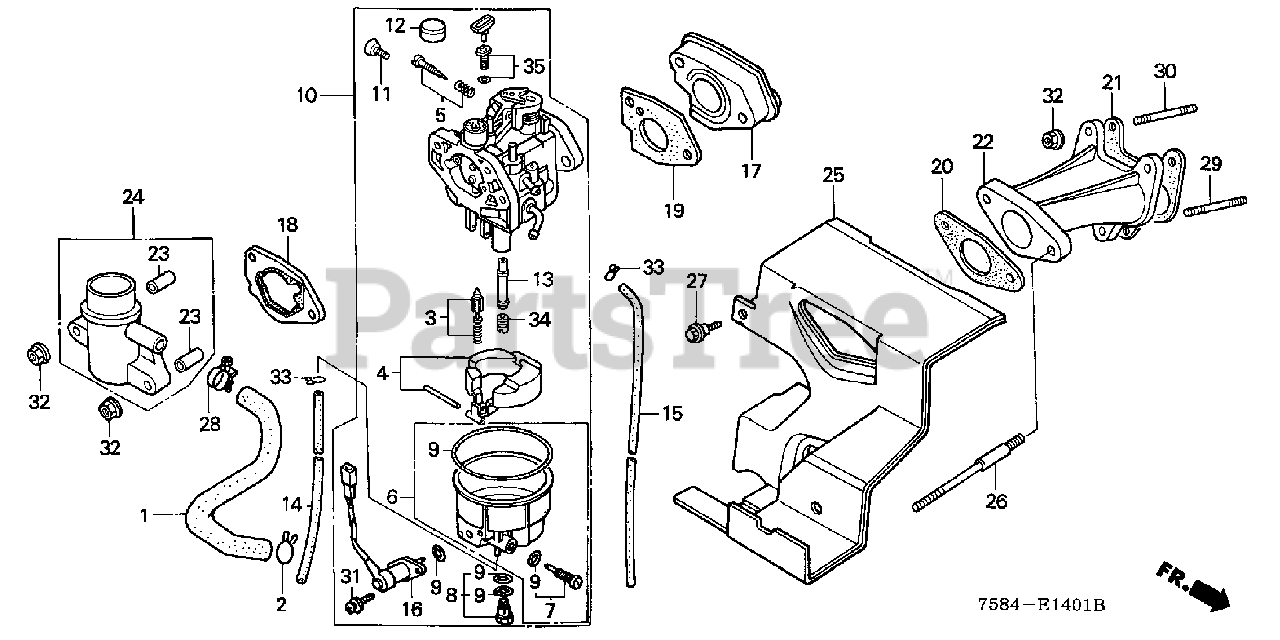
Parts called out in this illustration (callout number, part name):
1	TUBE, BREATHER
2	CLIP, BREATHER TUBE
3	VALVE SET, FLOAT
5	SCREW SET, PILOT
6	CHAMBER SET, FLOAT
7	SCREW SET, DRAIN
8	SCREW SET
9	GASKET SET (NOT AVAILABLE)
9	GASKET SET
10	CARBURETOR ASSY. (NOT AVAILABLE)
10	CARBURETOR ASSY. (BE27C B)
11	SCREW, THROTTLE STOP
12	CAP, CHOKE LEVER DUST
13	NOZZLE, MAIN
14	TUBE, FUEL DRAIN
15	TUBE, AIR VENT
16	VALVE ASSY., SOLENOID (NOT AVAILABLE)
16	VALVE ASSY., SOLENOID
17	INSULATOR, CARBURETOR
18	SPACER, CARBURETOR
19	GASKET, CARBURETOR
20	GASKET, INSULATOR
21	GASKET, IN. MANIFOLD
22	MANIFOLD, IN.
23	COLLAR, AIR CLEANER
24	ELBOW, AIR CLEANER
25	COVER, EX.
26	BOLT, STUD (8X138.5)
27	BOLT, FLANGE (6MM)
28	CLIP A18, TUBE
29	BOLT, STUD (6X32)
30	BOLT, STUD (6X28)
31	SCREW-WASHER (5X12)
32	NUT, FLANGE (6MM)
33	CLIP, TUBE (B8)
34	JET, MAIN (#88)
34	JET, MAIN (#90)
34	JET, MAIN (#92)
35	JET SET, PILOT (#45)
